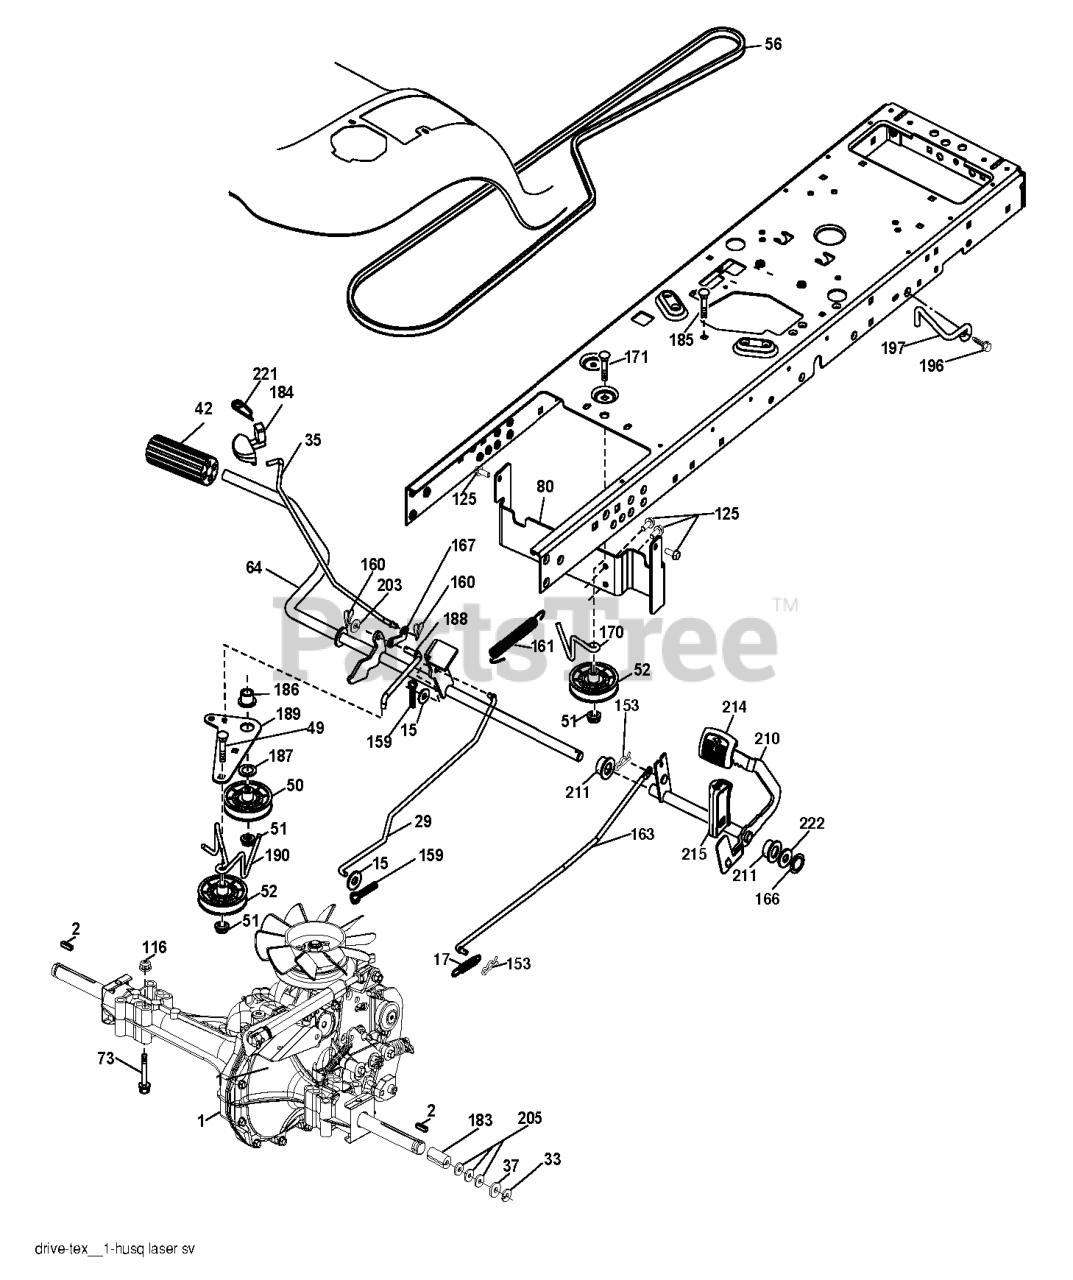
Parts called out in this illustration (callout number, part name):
2	SQUARE KEY
15	WASHER
17	SPRING.BRAKE.HG3000/3500
29	ROD.BRAKE.HG-0510
35	ROD.BRAKE.PARKING.LT.T
42	PEDAL COVER T
50	IDLER.FLAT.910.OFFSET
51	NUT LOCK FLG 3/8-16 UNC
52	IDLER.V-GROOVE.910.OFFSET
64	SHAFT.ASM.PEDAL.BRK.CNTR
73	BOLT HEX 5/16-18 GR 5
80	BRKT.STRP.TRQ.LT.HYD.C
116	NUT LOCK HEX FLANGE 5/16-18
125	SCREW
153	RETAINER M
159	COTTER PIN
160	RETAINER CLIP
161	SPRING.RETURN.CLUTCH.2006
163	ROD.PEDAL.CONTROL.0510
166	NUT.PUSH.625.2006
167	LATCH.BRAKE.SPRING
170	KEEPER.V-IDLER.CENTER.
183	SPACER AXLE
184	BOOT.STEERING.LT.TEX.P/L.418
186	SPACER.RETAINER
187	WASHER 12/32X2X10GA
188	RP.LINK.CLUTCH.GROUND.DRIVE
189	BELLCRANK.GROUND.DRIVE.TEX.
190	KEEPER.BELLCRANK.DRIVE
196	SCREW 3/8-16X1
197	LINK.CLUTCH.ANIT-ROTAT
203	WASHER
210	ROCKER.ASM.PEDAL.CONTR
211	BEARING.NYLON
214	PEDAL.FORWARD.TEX.GT.4
215	PEDAL.REVERSE.TEX.GT.4
221	RETAINER.SPRING.CLIP.H
222	WASHER 21/32 X 1-1/4 X 10 GA.
